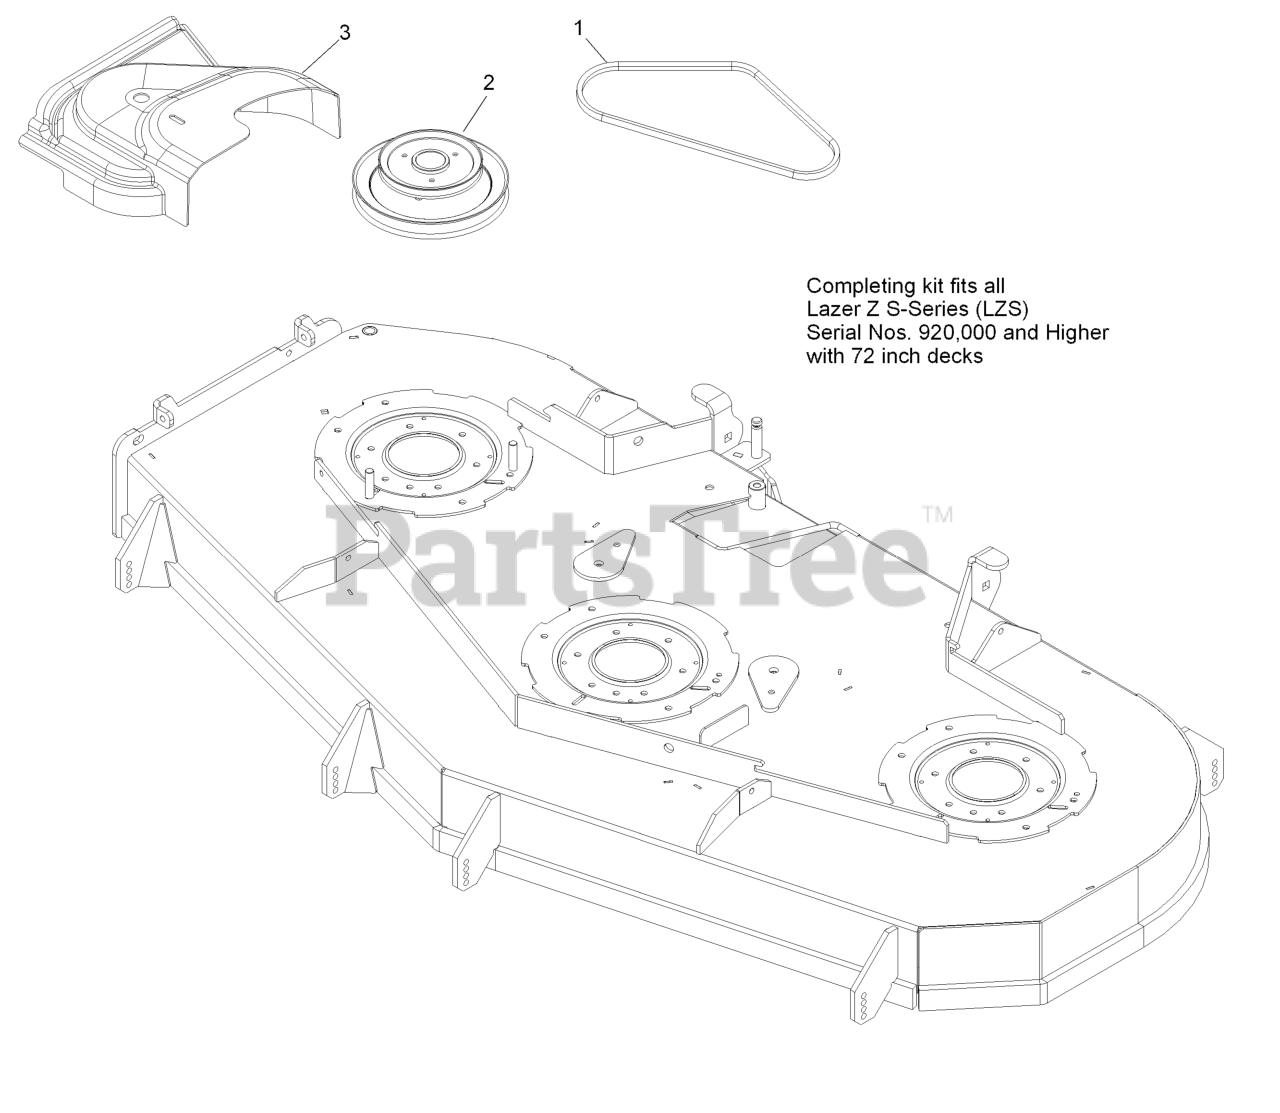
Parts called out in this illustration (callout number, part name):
1	Belt, Blower Drive 72
2	Jackshaft,Uv Drive 724 Splined
3	Cover,Belt Uv 72
